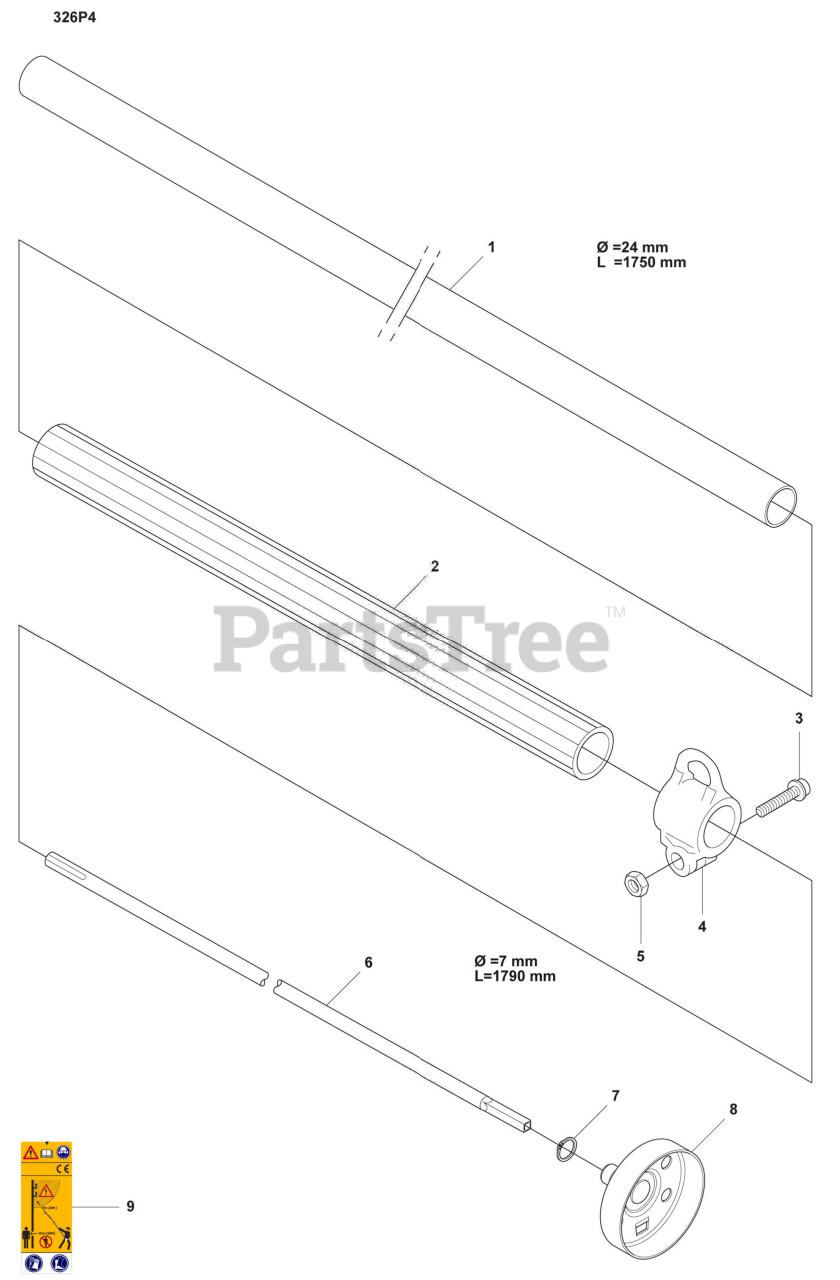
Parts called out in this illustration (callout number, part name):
1	Tube
3	Screw, M5 X 16 Ms Hsc Ih X
4	Harness Holder
5	Hex Nut, M5 X .80 DIN
6	Shaft, P4
8	Clutch Drum
